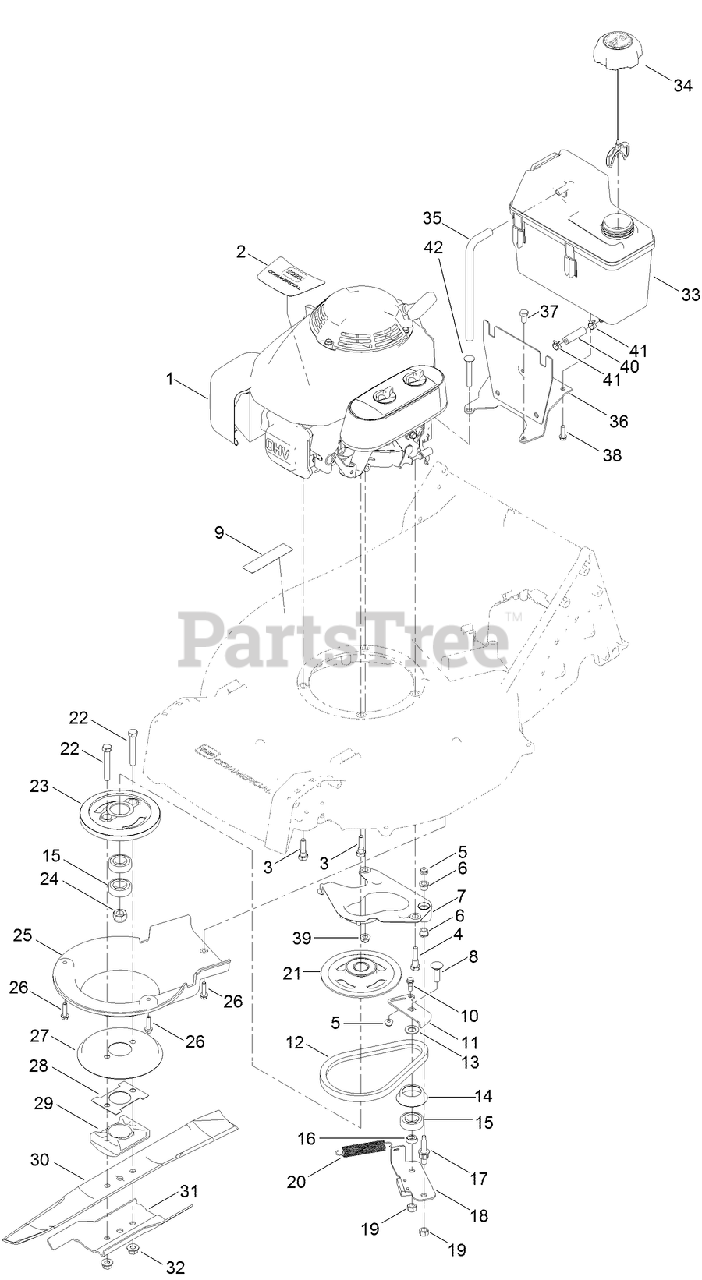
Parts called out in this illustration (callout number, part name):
1	ENGINE-HONDA, GXV160 GAS
2	DECAL-ENGINE, HONDA
3	SCREW-HHSH
4	SCREW-SHOULDER
5	NUT-HF
6	BUSHING-FLANGE
7	PLATE-ANCHOR
8	BOLT-CARR
9	DECAL-ARRESTOR, SPARK
10	BOLT-SHOULDER
11	PLATE-GUIDE, BBC
13	SPACER
14	RETAINER-BELT
15	BEARING-BALL
16	SPACER-BEARING
17	BOLT-SHOULDER
18	PLATE-BRAKE
19	NUT-HEX
20	SPRING-TENSION, BRAKE
21	PULLEY
22	SCREW-HH
24	NUT-HEX
26	SCREW-HWHTF
27	DISC
28	SPACER-DRIVER, BLADE
29	SUPPORT-BLADE
30	BLADE-21IN, RECYCLING
31	ACCELERATOR-BLADE
32	NUT-FLANGE, LOCK
33	TANK-FUEL
34	CAP-FUEL
35	HOSE-VENT, CANISTER
36	MOUNT-TANK
37	SCREW-HH
38	SCREW-HWH
39	NUT-HF, NI
40	HOSE-FUEL
41	CLAMP-HOSE
42	BOLT-CARR
